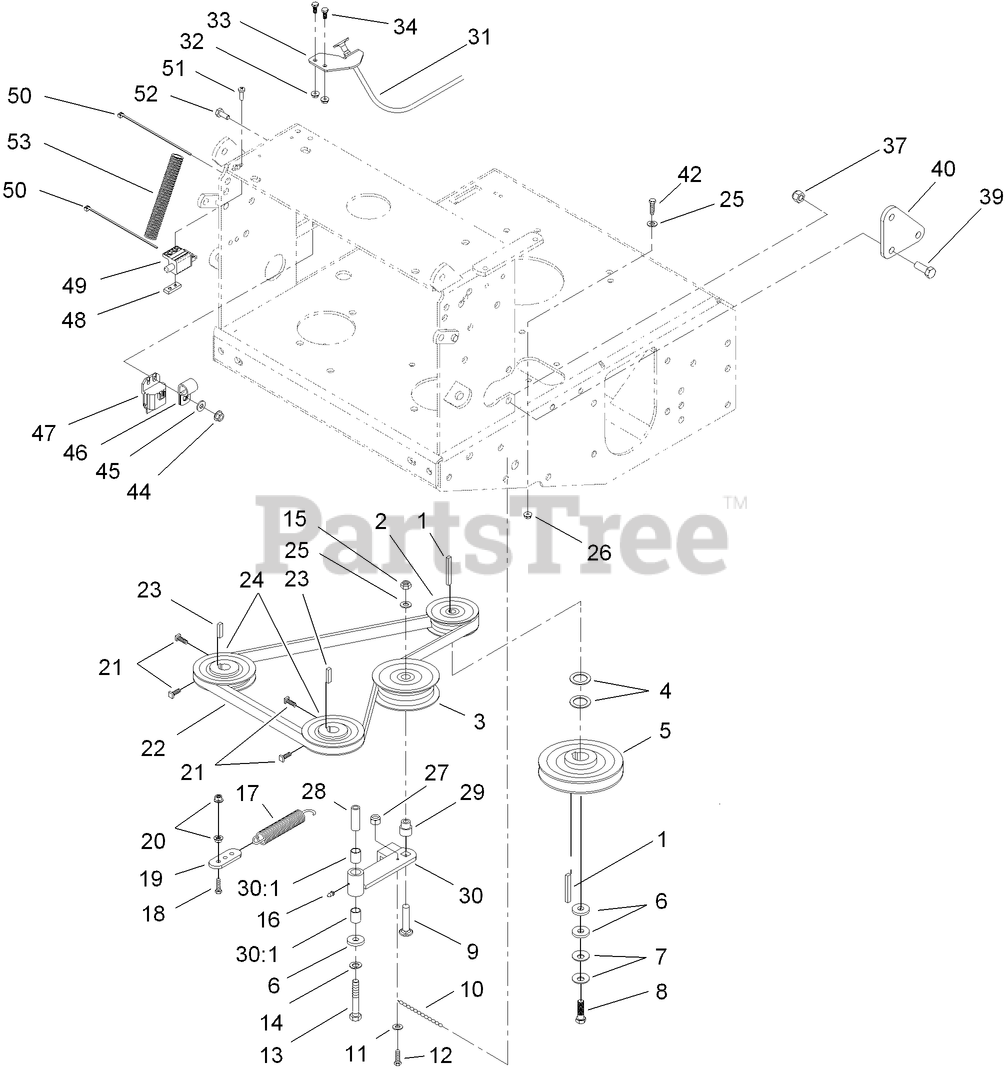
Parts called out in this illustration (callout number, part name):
2	PULLEY
3	PULLEY-IDLER
4	WASHER-SPACER
5	PULLEY
6	WASHER
7	WASHER-SPRING
8	SCREW-HH
9	SCREW-CARR
10	Chain-Link, Twist
11	WASHER-FLAT
12	SCREW-HSH
13	SCREW-HH
14	WASHER
15	NUT-HF
16	FITTING-GREASE
17	SPRING-EXTENSION
18	SCREW-HH
19	Anchor-Spring
20	NUT-HF
21	SCREW-SET
22	V-BELT
24	SHEAVE ASM
25	WASHER-FLAT
26	NUT-HHF, WHIZ
27	NUT-LOCK, NI
28	BUSHING
29	BUSHING-IDLER
30	Idler Arm ASM
30:1	SLEEVE-BEARING
31	Cable-Choke
32	NUT-HF
33	Bracket-Cable, Choke
34	SCREW-HH
37	NUT-LOCK, NI
39	SCREW-HH
40	Bellcrank
42	SCREW-HH
44	NUT-LOCK, NI
45	WASHER-FLAT
46	CLIP-LOOM
47	MODULE-INTERLOCK
48	PLATE-TAPPED
49	SWITCH-OPEN, NORMALLY
50	TIE-CABLE
51	SCREW-PPH
52	SCREW-HH
53	TUBING-CONVOLUTED
